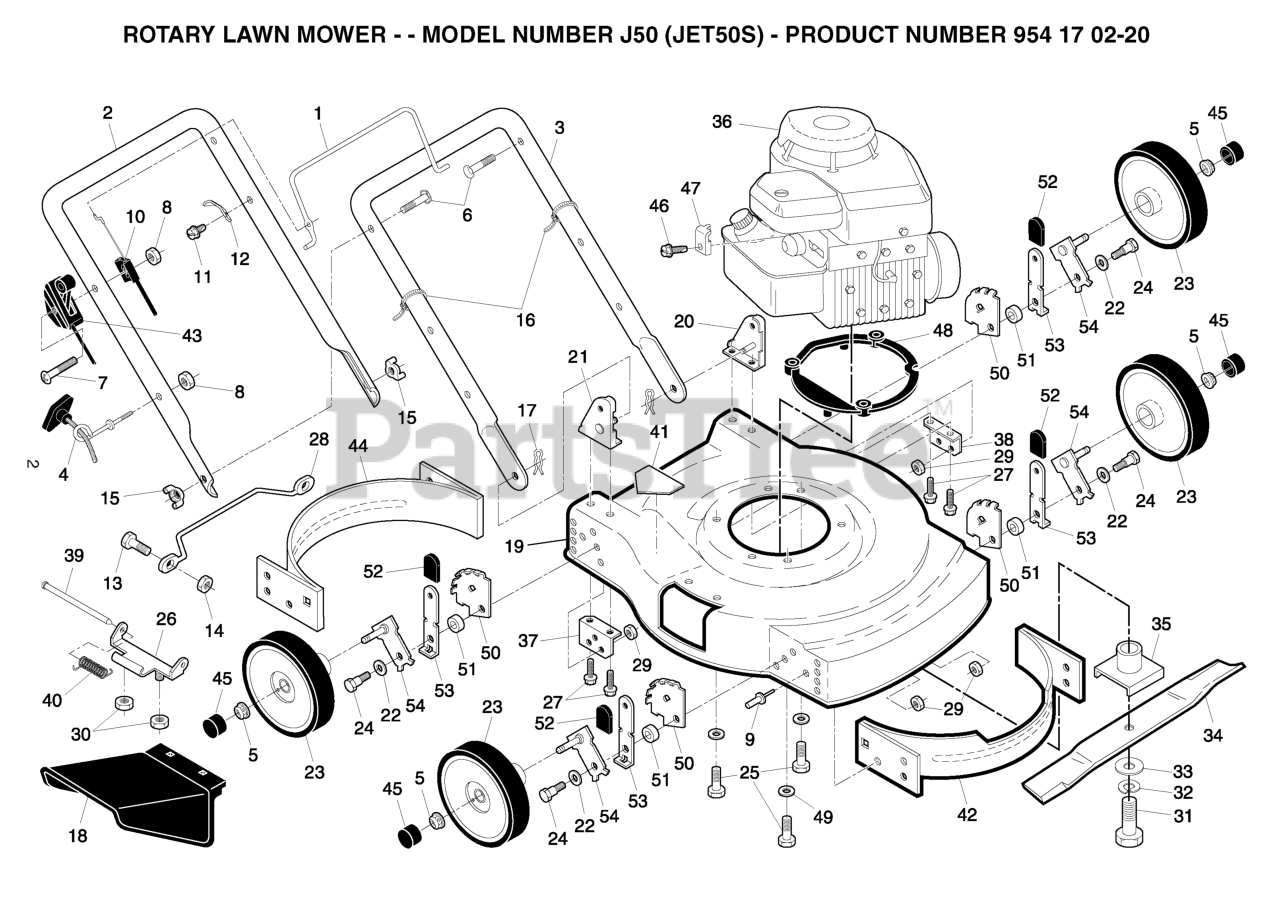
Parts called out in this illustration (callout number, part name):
1	CONTROL BAR
2	UPPER HANDLE
3	HANDLE
4	ROPE, GUIDE
5	HEX FLANGE LOCKNT
6	HANDLE BOLT
8	NUT
9	RIVET BLIND
10	CABLE.MZR.51.RT.SP./PU.
12	BRACKET UPSTOP
13	REPL BY 817 02 10-08
15	NUT WING PM
16	TIE GUIDE
17	HAIRPIN COTTER
20	HANDLE BRACKET ASM. LH
21	HANDLE BRACKET ASM. RH
22	WASHER.BELLEVILLE (3 2 LB)
23	WHEEL
24	BOLT
26	BRACKET PM
27	SCREW.5/16-18X3/4
29	LOCKNUT PM
30	LOCKNUT.NYLOC.1/4-20
31	SCREW, HEX HD 3/8-24 X 1-3/8
32	LOCKWASHER
33	WASHER,HARDEN
34	20" Blade
35	BLADE ADAPTOR
39	ROD.HINGE.COMBI-C
41	DECAL.INTERNATIONL.CUTFINGER
43	THROTTLE CONTROL
46	SCREW.HEX.HEAD.WASHER.10-16
47	CABLE CLAMP(ENGINE)
50	WHEEL ADJUST BRACKET
51	RP SPACER HT ADJ
53	SELECTOR SPRING
54	AXLE, REAR
